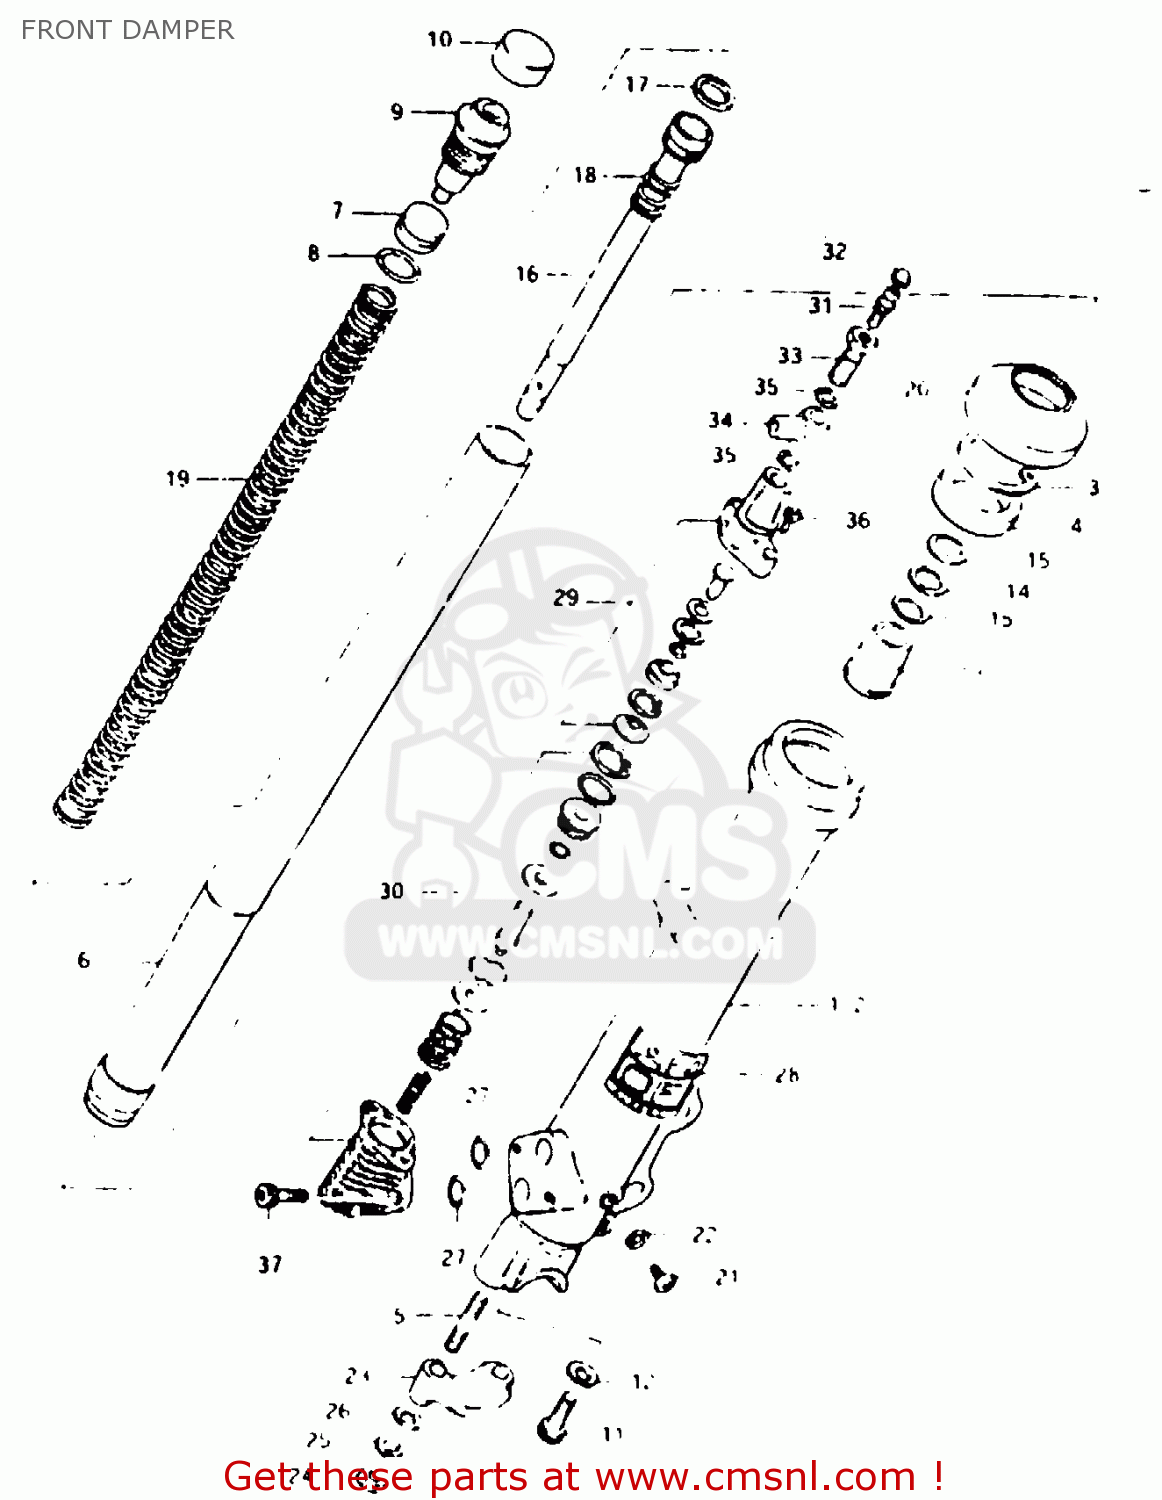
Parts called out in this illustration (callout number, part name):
1	OUTER TUBE, RH
2	OUTER TUBE, LH
3	RING,STOPPER
4	OIL SEAL,FRONT FORK
5	STUD 8X30
6	TUBE,INNER
7	PISTON,FREE
8	O-RING
9	CAP
10	CAP,RUBBER
11	BOLT,FORK CYLINDER(10X25)
12	GASKET (NAS)
13	PIECE,OIL LOCK
14	WASHER
15	SPRING,LEAF
16	CYLINDER,FRONT FORK
17	RING,PISTON
18	SPRING,REBOUND
19	SPRING,FRONT FORK
20	SEAL,DUST
21	SCREW
22	GASKET,DRAIN,PLUG (NAS)
23	HOLDER,AXLE
24	NUT (8MM)
25	LOCK WASHER
26	WASHER
27	O RING
28	LABEL
29	MODULATOR PLANGER SET
30	MODULATOR VALVE SET
31	BREATHER,AIR
32	CAP,BREADER
33	BOLT,UNION
34	SPACER,FRONT FORK MODULATOR
35	WASHER
36	BOLT,FR FORK
37	BOLT,FRONT FORK
